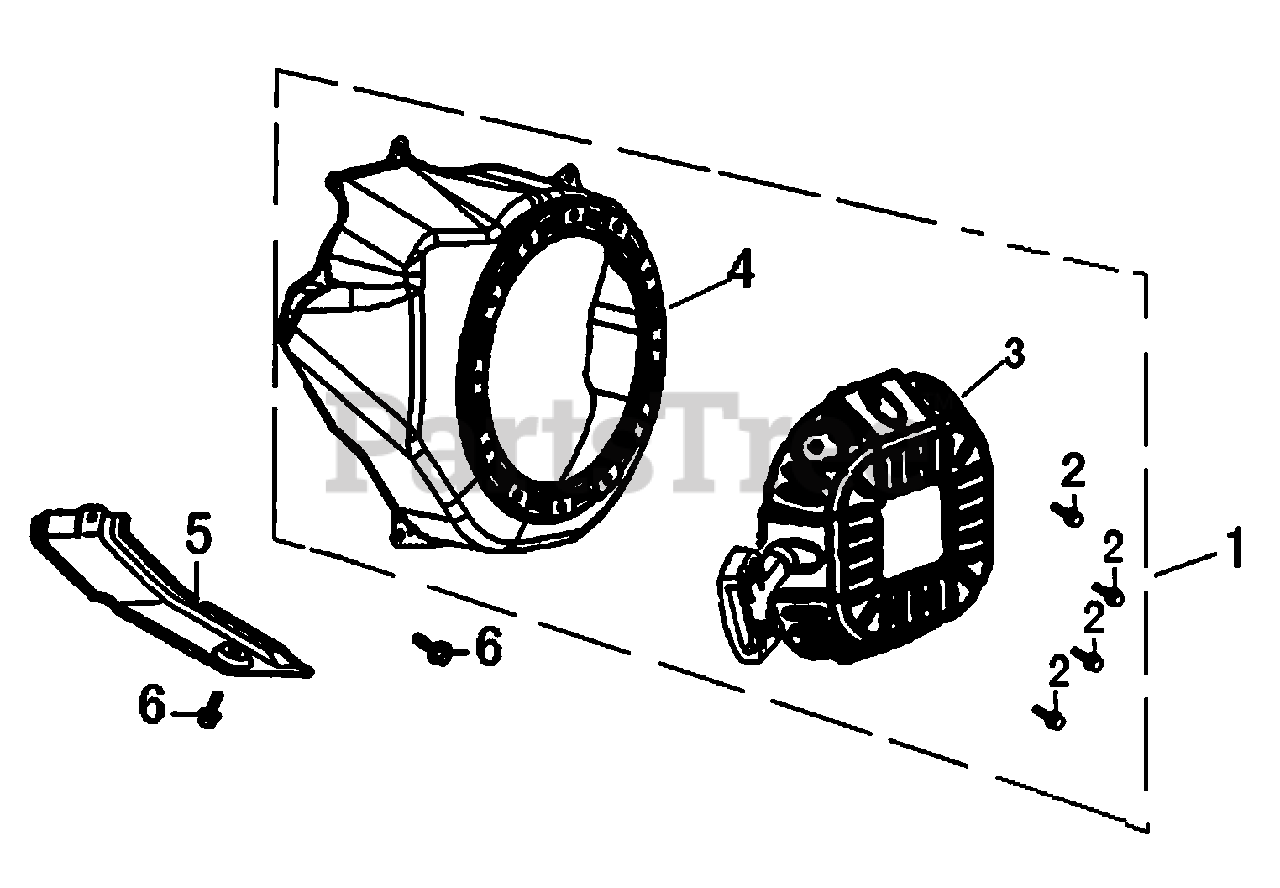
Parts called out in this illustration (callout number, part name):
1	STARTER, RECOIL W/HSNG.
2	BOLT, FLANGE 6X8
3	STARTER ASSY.
4	COVER COMP., FAN
6	BOLT, FLANGE 6X12
